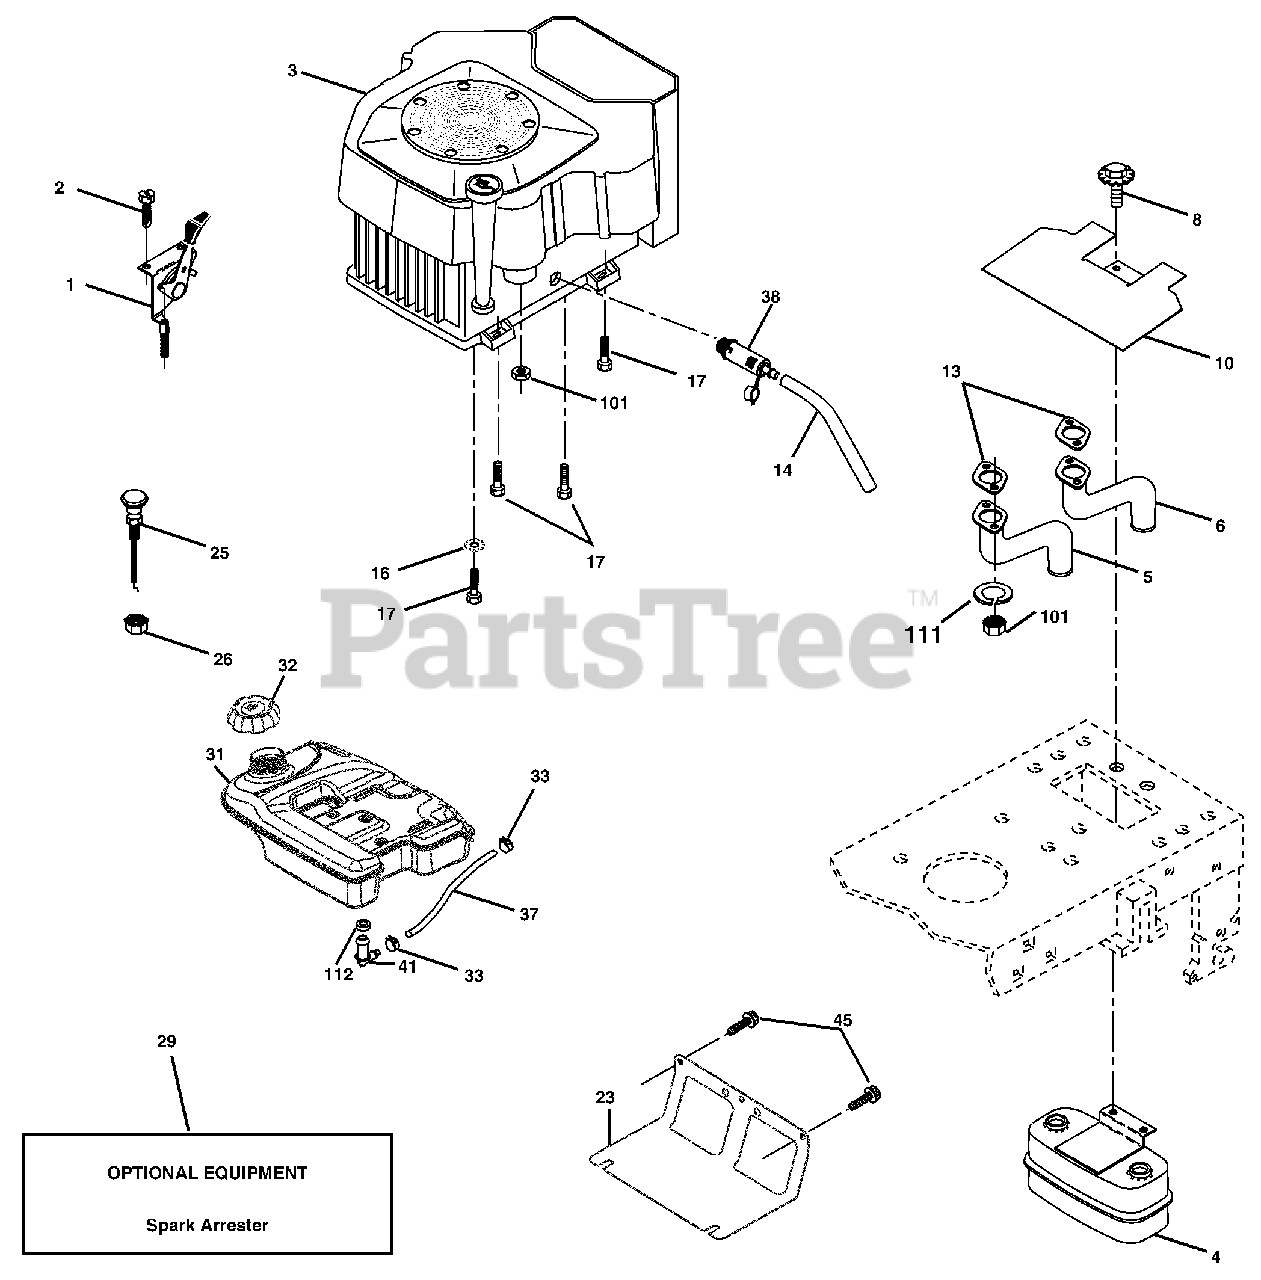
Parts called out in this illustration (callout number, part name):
1	Control Throttle
2	Screw Hw Hd Hi-Lo #13-16 x 3/4
4	Muffler Asm Twin Lo-Tone
5	Pipe Exhaust LH
6	Pipe Exhaust RH
8	Bolt 5/16-18 UNC x 3/4 w/Sems
10	Shield Heat Muffler
13	Muffler Gasket
14	Tube Drain Oil Easy
17	Screw Thdrol 3/8-16 x 1-1/2
23	Shield Heat
25	Choke Control
26	Nut, Keps 3/8-24 UNF
29	Kit Spark Arrestor (Flat Scrn)
31	Tank Fuel 4.0 Rear
32	Cap Asm Fuel
33	Clamp Hose Black
37	Line Fuel
38	Plug Drain Oil
41	Stem Tank Fuel
45	Screw Hexwsh Thdr 3/8-16 x 3/4
101	Nut Flange
111	Washer Split
112	Bushing
